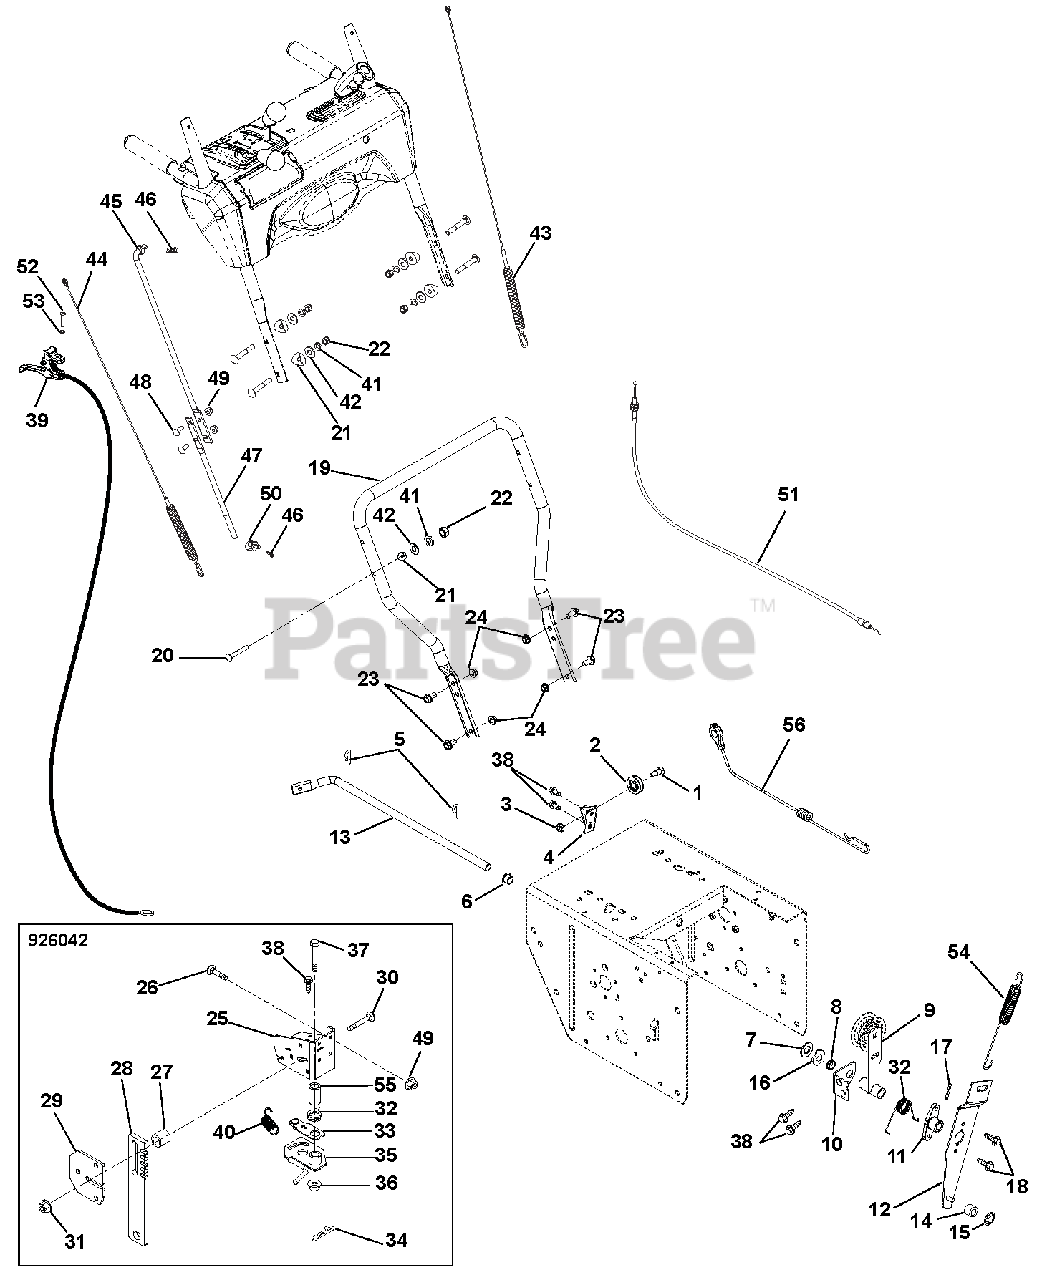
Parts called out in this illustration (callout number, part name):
1	BOLT, SHLDR-.375X.375X.25-20
2	PULLEY, CABLE
3	@NUT-LK-TOP-FLG .25-20 YWZC
4	BRACKET, CABLE PULLEY
5	CLIP, SPRING
6	BUSHING, POLYLINER-.50 SPLIT
7	@WSHR-FL-STL.531X1.06X.095YWZC
8	BUSHING, POLYLINER-.50 SNAPIN
9	ARM, IDLER-TRACTION
10	BRACKET, SUPPORT
11	HUB, BRAKE ARM
12	ARM, IDLER-ATTACHMENT
13	ARM, ATTACHMENT
14	BSHG,SLV .265 X .625 X .375
15	RG-RTNG-EXT .250X.010
16	WAVE WASHER .531X.781X.125FH
17	PIN-ROLL .125X1.00
18	SCR-TAP .25-20X.75 HWH TR YWZ
19	HANDLEBAR, LOWER
20	@BLT-RDHDSQNK .31-18X2.25 G5YZ
21	SPACER, HANDLEBAR
22	@NUT-LK-NYL .312-18 YWZC
23	BLT-SERHFWH .38-16X.75 YWZC
24	@NUT-LK-TOP-FLG .38-16 YWZC
25	BRACKET, HEIGHT ADJUSTER-PRO
26	@BLT-RDHDSQNK .25-20X.75 G5YZ
27	SPACER .50 X .32 X .42
28	STOP, HEIGHT ADJUSTER-PRO
29	PLATE, HEIGHT ADJUSTER
30	@BLT-RHDSHSQNK.31-18X1.25 G5YZ
31	@NUT-LK-TOP-FLG .31-18 YWZC
32	SG-TORS .067X.88
33	ARM, OVERTRAVEL
34	PIN-HAIR INT .06X.18X.77
35	LOCK, HEIGHT ADJUSTER
36	NUT-LK-CTR-FLG .38-16 YWZC
37	@BLT-HEX .38-16X1.75 GR5 YWZC
38	SCR-TAP .25-20X.50 HWH TR YWZ
39	CABLE, TRACK REMOTE
40	SPRING-EXT .047 X .438 X 1.85
41	WSHR-LK .312X.097 HVY YWZC
42	@WSHR-FL-STL.38X.875X.083 YWZC
43	CABLE, UPPER TRACTION
44	CABLE, AUGER (DELUXE & PRO)
45	ROD, SHIFT - UPPER
46	PIN-HAIR INT .08X.18X1.18 YWZC
47	ROD, SHIFT - LOWER
48	@BLT-RDHDSQNK .25-20X.75 G5YZ
49	@NUT-LK-TOP-FLG .25-20 YWZC
50	PIVOT,SHIFT ROD .375-16(TRUNN)
51	CABLE, CHUTE LOCK
52	SCR-MCH .25-20X1.50 OVAL HD
53	WSHR-LK-INT .250 TH TYA
54	SG-TENS .06X.482X5.35
55	BSHG-SLV .385X.500X1.045
56	CABLE, LOWER TRACTION,SS & PRO
